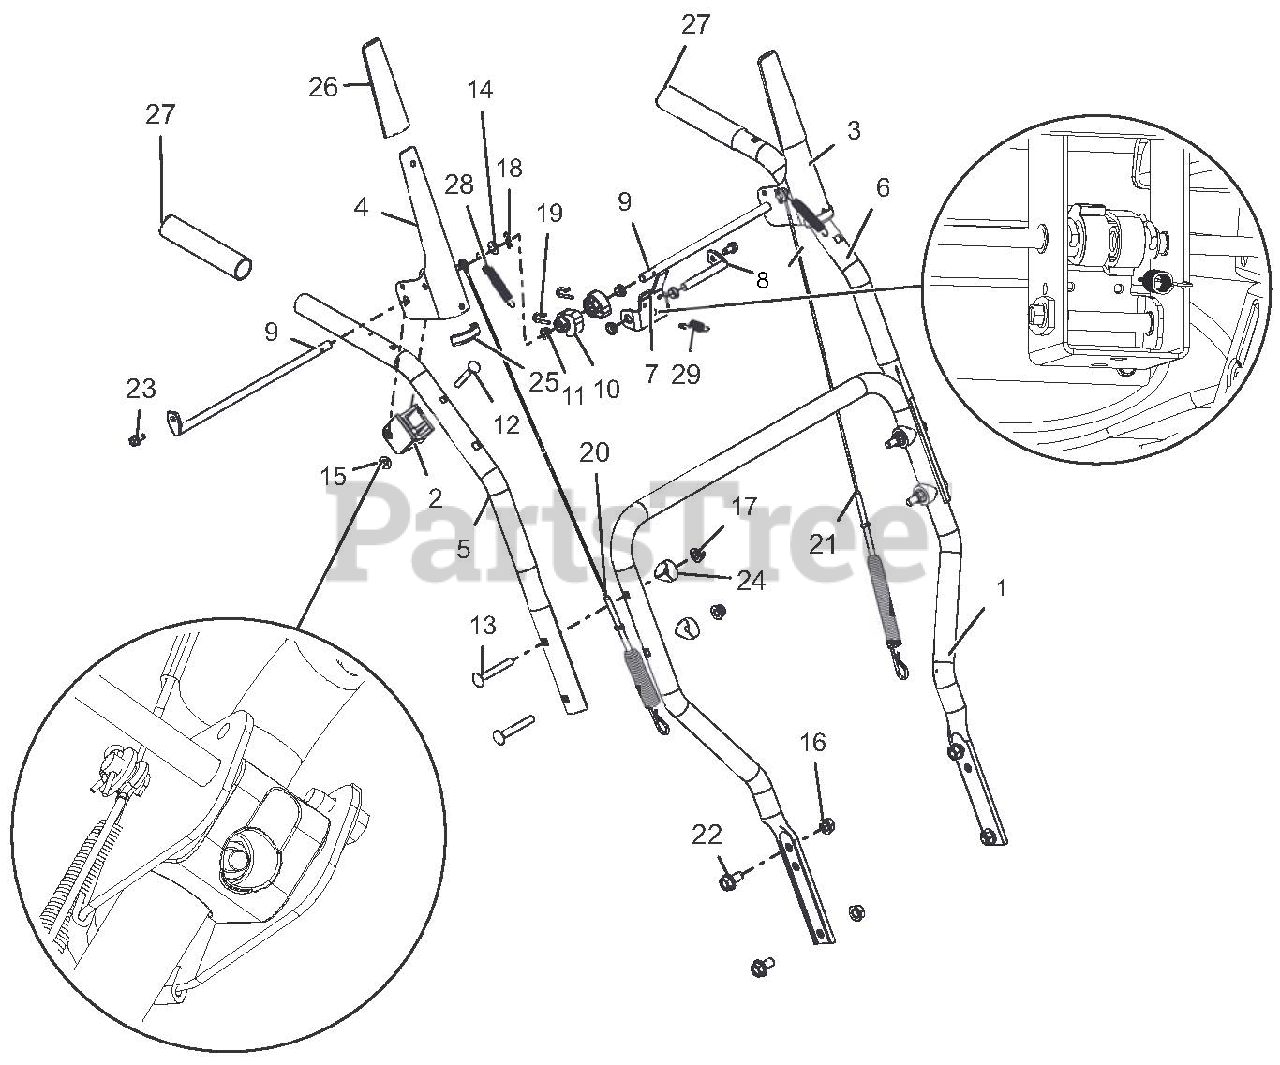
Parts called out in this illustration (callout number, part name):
1	HANDLEBAR, LOWER
2	BLOCK, CLUTCH PADDLE
3	LEVER, CLUTCH-LH
4	LEVER, CLUTCH-RH
5	HANDLEBAR, UPPER - RH
6	HANDLEBAR, UPPER - LH
7	BRACKET, INTERLOCK ARM
8	ROD, PIVOT - INTERLOCK
9	ROD, PADDLE MOUNT - PRO
10	CAM, INTERLOCK
11	BUSHING, POLYLINER-.38 SNAPIN
12	BLT-RDHDXLSQNK .25-20X2.0 G5YZ
13	@BLT-RDHDSQNK .31-18X2.25 G5YZ
14	@WSHR-FL-STL.281X.62X.065 YWZC
15	@NUT-LK-CTR-FLG .25-20 YWZC
16	@NUT-LK-TOP-FLG .38-16 YWZC
17	@NUT-LK-NYL-FLG .31-18 YWZC
18	PIN-HAIR INT .06X.18X.77
19	PIN, SPRING CLIP
20	CABLE, AUGER (DELUXE & PRO)
21	CABLE, UPPER TRACTION
22	BLT-SERHFWH .38-16X.75 YWZC
23	SCR-TAP .25-20X.50 HWH TR YWZ
24	SPACER, HANDLEBAR
25	EDGING, CLUTCH PADDLE - 2.00"
26	CLUTCH PADDLE SLEEVE - GRAY
27	HANDLE GRIP
28	SPRING, EXTENSION
29	SPRING-EXT .047X.438X1.45
